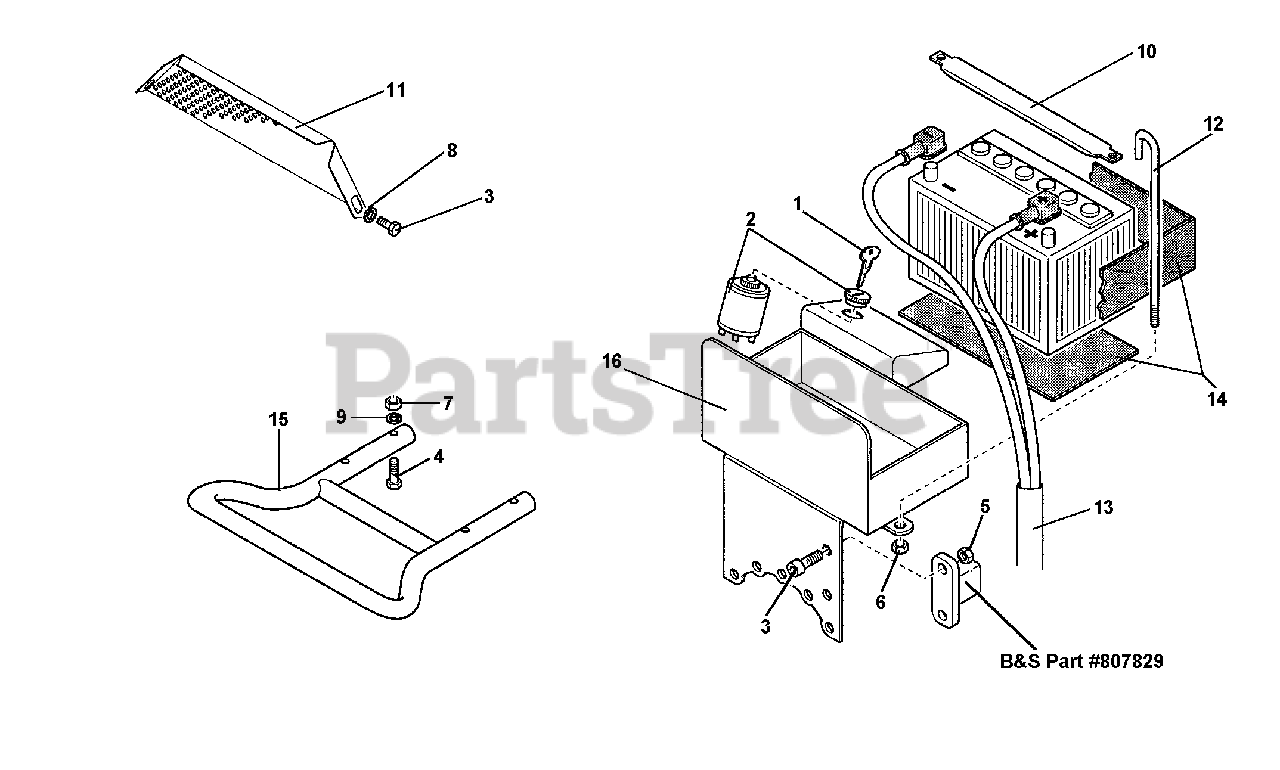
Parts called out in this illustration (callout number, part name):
3	SCREW M6X10
4	SCREW M8X70 VANGARD ENGINE
6	NUT, SELF LOCKING M6
7	NUT, SELF LOCKING M8
8	WASHER, FLAT 6.4
9	WASHER, LOCK 8.4
10	BATTERY BRACKET
11	ENGINE COVER
12	BATTERY TIEROD
13	ELECTRIC STARTER CABLES, VANGARD
14	BATTERY PADS
15	BUMPER, VANGARD
16	BATTERY SUPPORT
